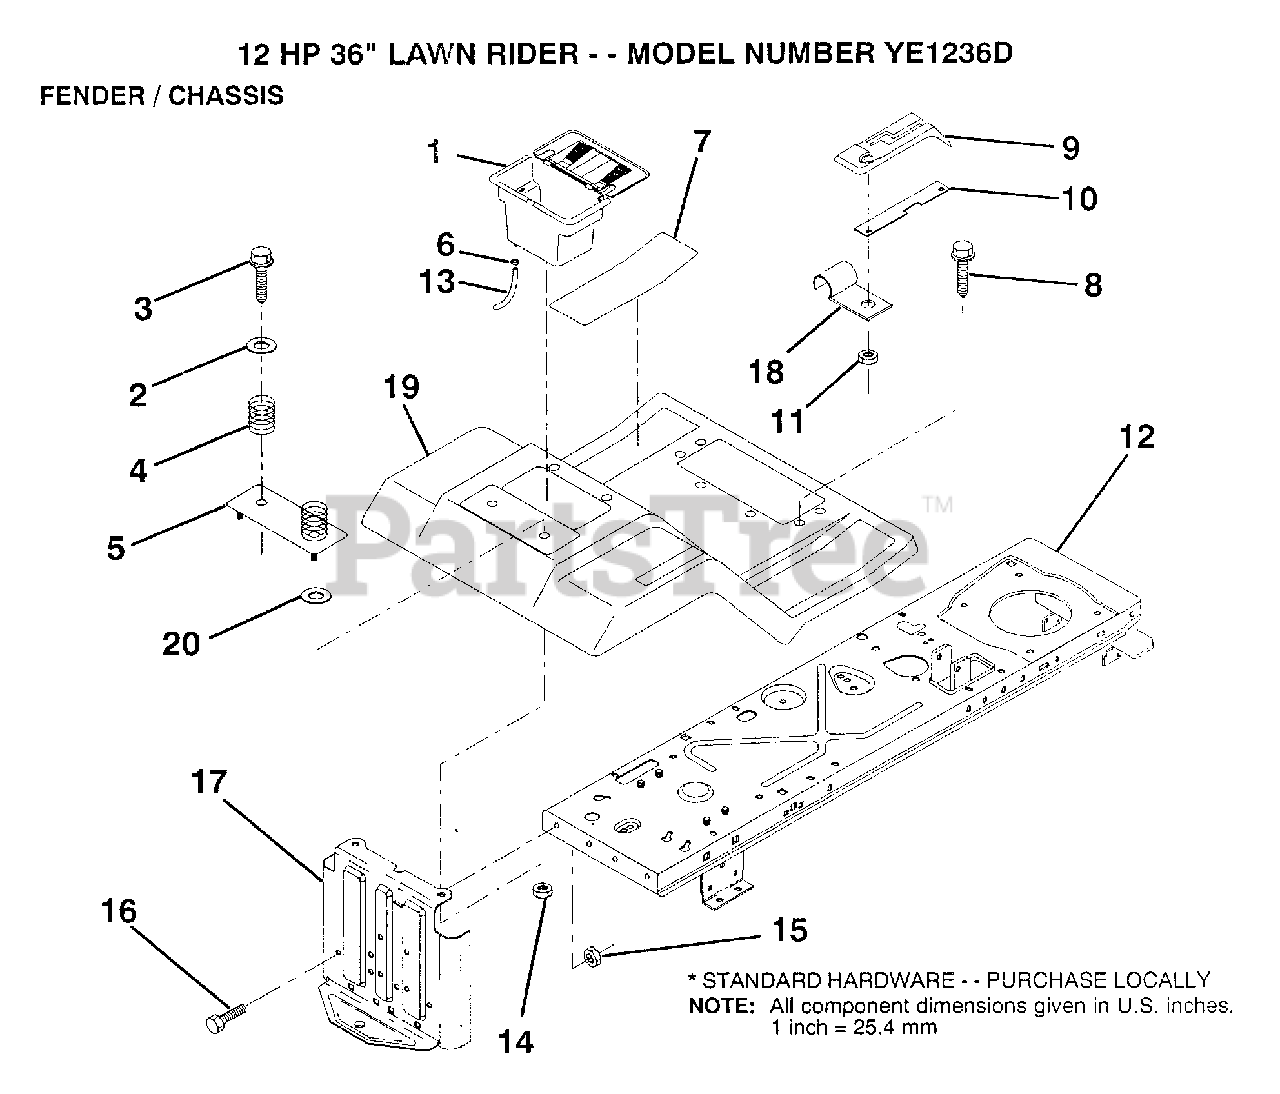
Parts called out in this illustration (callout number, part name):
2	WASHER
3	SCREW
4	SPRING COMPRESSIO
5	BTRY FENDER PLATE
6	HOSE CLAMP T
7	PAD FOOTREST
8	SCREW
10	"SHIFT LOCK, BAR"
11	NUT
14	NUT
16	BOLT
17	DRAWBAR
18	"CLIP,INSULATOR"
